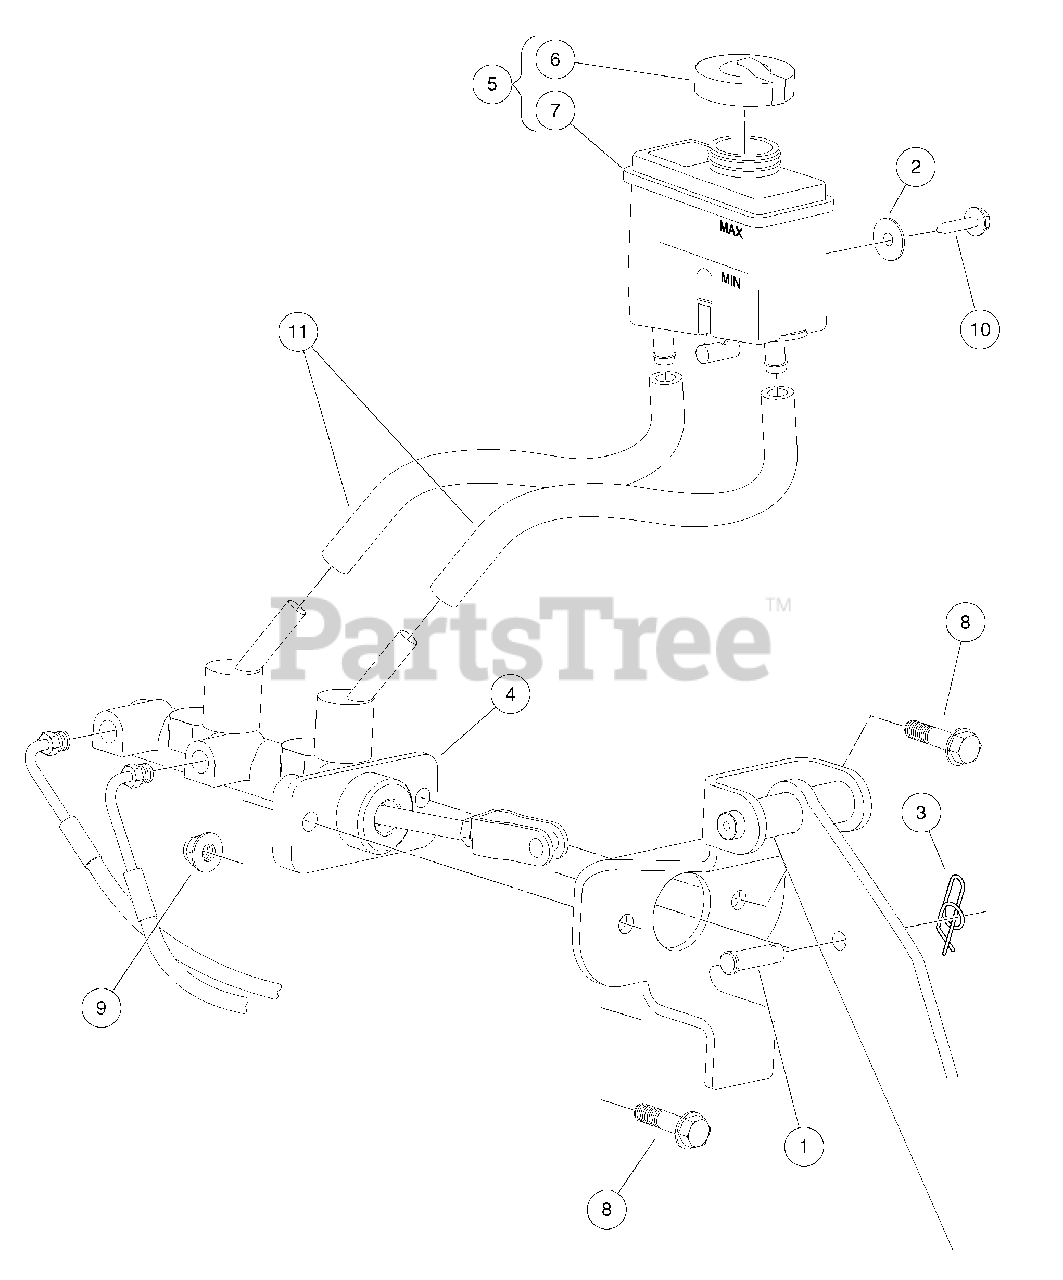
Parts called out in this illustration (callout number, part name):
1	Clevis Pin, 5/16 X 1
2	Washer, 1/4" Type B Flat
4	Cylinder, Master, Tandem
5	Assembly, Reservoir, Remote
6	Filler Cap Asm
7	Reservoir, Brake Fluid, Without Cap
8	Bolt Flanged Head, M8 X 1.25 X 35
9	Lock Nut, Flg M8 X 1.25 Nylon
10	Screw, #10x3.50 Ab Thd, Hex Hd
11	Hose, Reservoir, Brake Fluid
